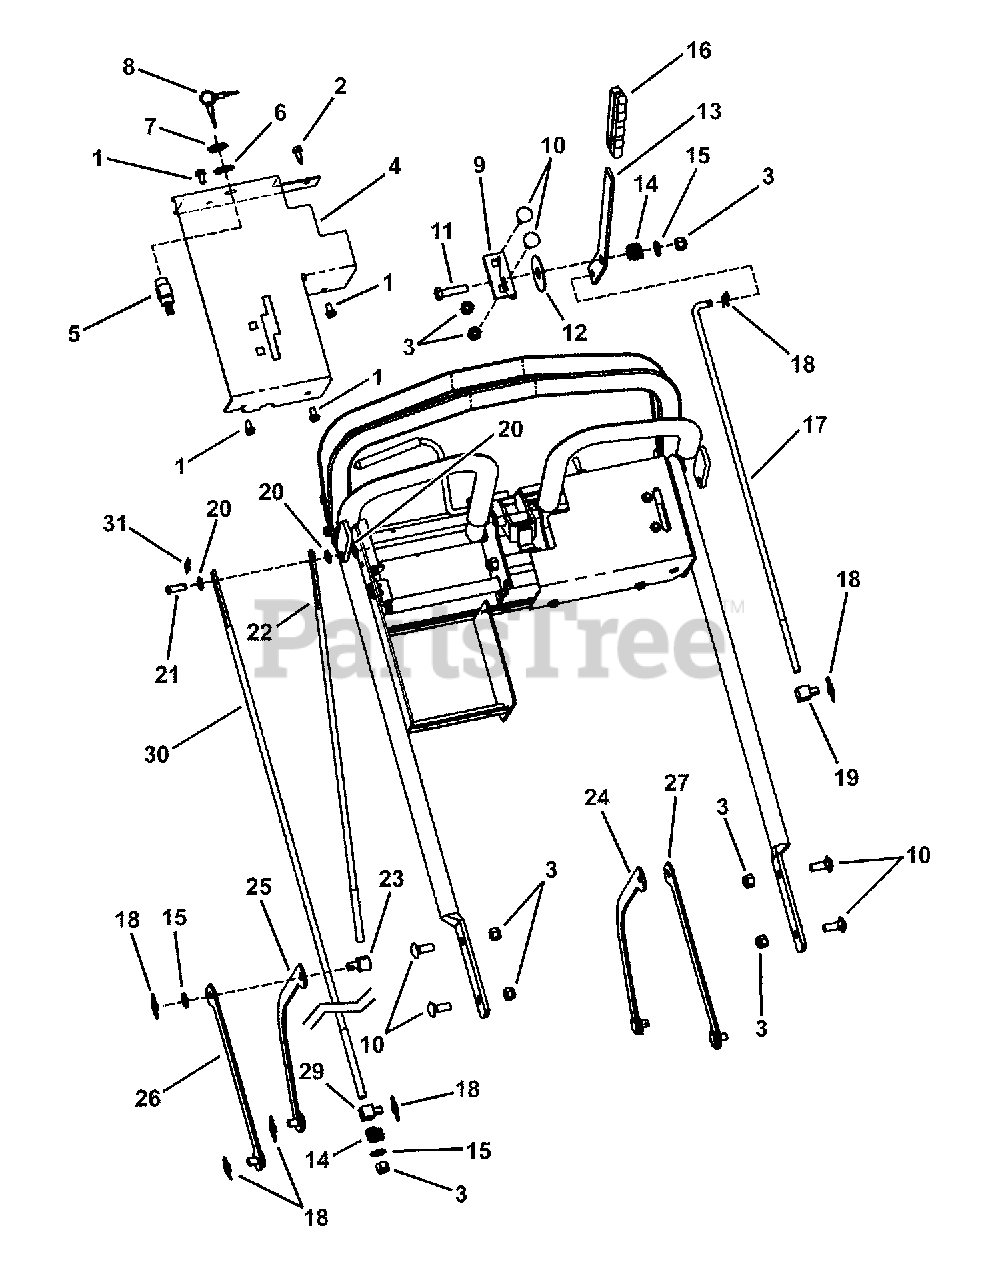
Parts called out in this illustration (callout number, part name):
1	SCREW, 1/4-20 x 1/2" Hex Washer Self-Tap
2	SCREW, 1/4-20 x 3/4" Hex Washer Self-Tap
3	NUT, 3/8-16 HEX NYLON LOCK
4	PANEL, Console RH
5	SWITCH, On-Off
6	WASHER, 5/8" Internal Tooth Lock
7	NUT, 5/8-32 Hex (Special)
8	KEY, Ignition (Pair)
9	BRACKET, Shift Handle
10	BOLT, 3/8-16 x 1" Square Neck Carriage, GR 5
11	SCREW, 3/8-16 x 1-1/2" Hex Head Cap, GR 5
12	SPACER, Wear
13	SHIFT LEVER
14	SPRING, Friction Pack
15	WASHER, 3/8" SAE Flat
16	GRIP, Flat Bar (Black)
17	ROD, Shift (21-1/2" long, 3/8-16 thread)
18	COTTER PIN, 1/2" Self-Locking
19	SWIVEL, Brake Link, 3/8-16 thread
20	WASHER, 5/16" Flat
21	PIN, 5/16 x .94 Clevis
22	ROD, Traction (22" Long, 3/8-16 Thread)
23	SWIVEL, 3/8-16 Thread, .109 Dia. Hole
24	TRACTION LINK, Lower Left (Weldment)
25	TRACTION LINK, Lower Right (Weldment)
26	TRACTION LINK, Upper Right (Weldment)
27	TRACTION LINK, Upper Left (Weldment)
29	SWIVEL, .406 & .109 Dia. Holes
30	ROD, Brake (37-3/4" Long, 3/8-16 Thread)
31	COTTER PIN, 5/16 Self Lock
